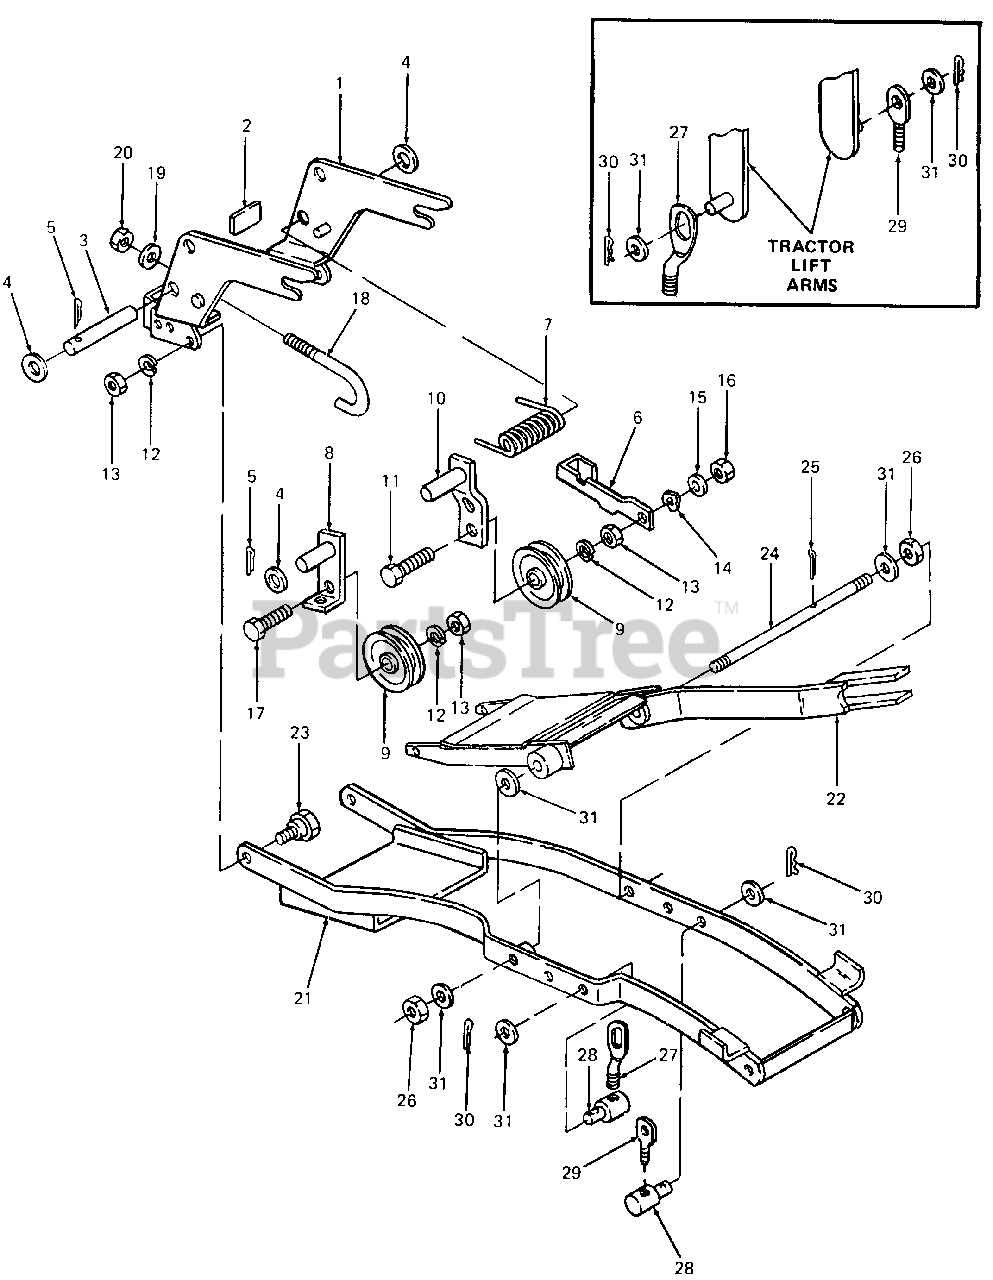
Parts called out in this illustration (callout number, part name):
1	Hanger Assy, Front
2	Graphic, Idler Adjustment
3	Shaft, Idler Pivot
4	Washer, Flat, .640 X .943 X .050
5	Pin, Cotter, 1/8 Dia X 1.0
7	Spring, Idler Torsion
8	Arm Assy, Idler LH
9	Pulley, Idler
10	Arm Assy, Idler RH
11	Screw, Hex Cap, 3/8-16 X 2.25 Lg GR5
12	Washer, Lock, 3/8
13	Nut, Hex, 3/8-16 GR5
14	Washer, Wave, .406 X .64 X .015
15	Washer, Flat, .405 X .75 X .06
16	Nut, Hex Center Lock, 3/8-16 GR5
17	Screw, Hex Cap, 3/8-16 X 1.5 Lg GR5
18	Bolt, Idler Adjuster
19	Washer, Flat, .34 X .68 X .062
20	Nut, Hex Center Lock, 5/16-18 GR5
24	Shaft, Pivot
25	Pin, Cotter, 1/8 Dia X 1.25
26	Nut, Hex Jam w/Plastic Patch
27	Link, Offset Adjustable
28	Ferrule, Adjustment
29	Link, Adjustable
30	Pin, Internal Cotter
31	Washer, Flat, .510 X 1.0 X .060 Thk
